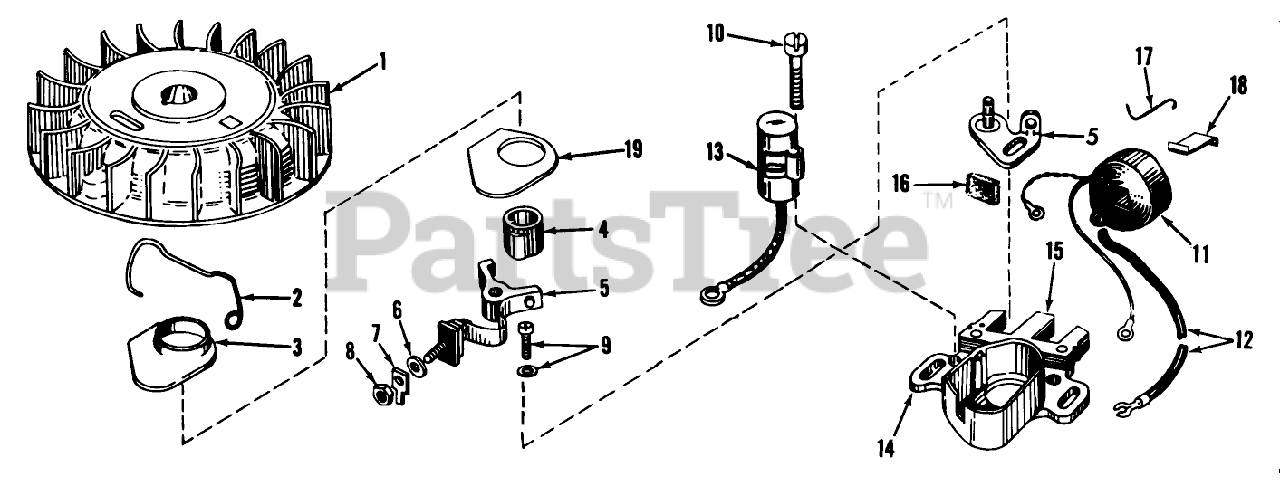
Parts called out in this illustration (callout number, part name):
1	Flywheel
2	Spring Breaker Box
3	Cover, Dust
4	Cam-Breaker
5	Breaker Assy.
6	Washer
7	Terminal
8	DECAL
9	Breaker Screw
10	Condenser Screw
11	Coil Assy., (Inc. Ref. Nos. 12, 13 18)
12	Wire, Lead
13	Condenser
14	Core Plate
15	Stator Assy., (Incl. Nos. 2, 3, 5 thru 14 16 thru 19)
16	Felt,Cam Wiper
17	Clip, Coil
18	Spring Coil Wedge
19	Gasket Dust
